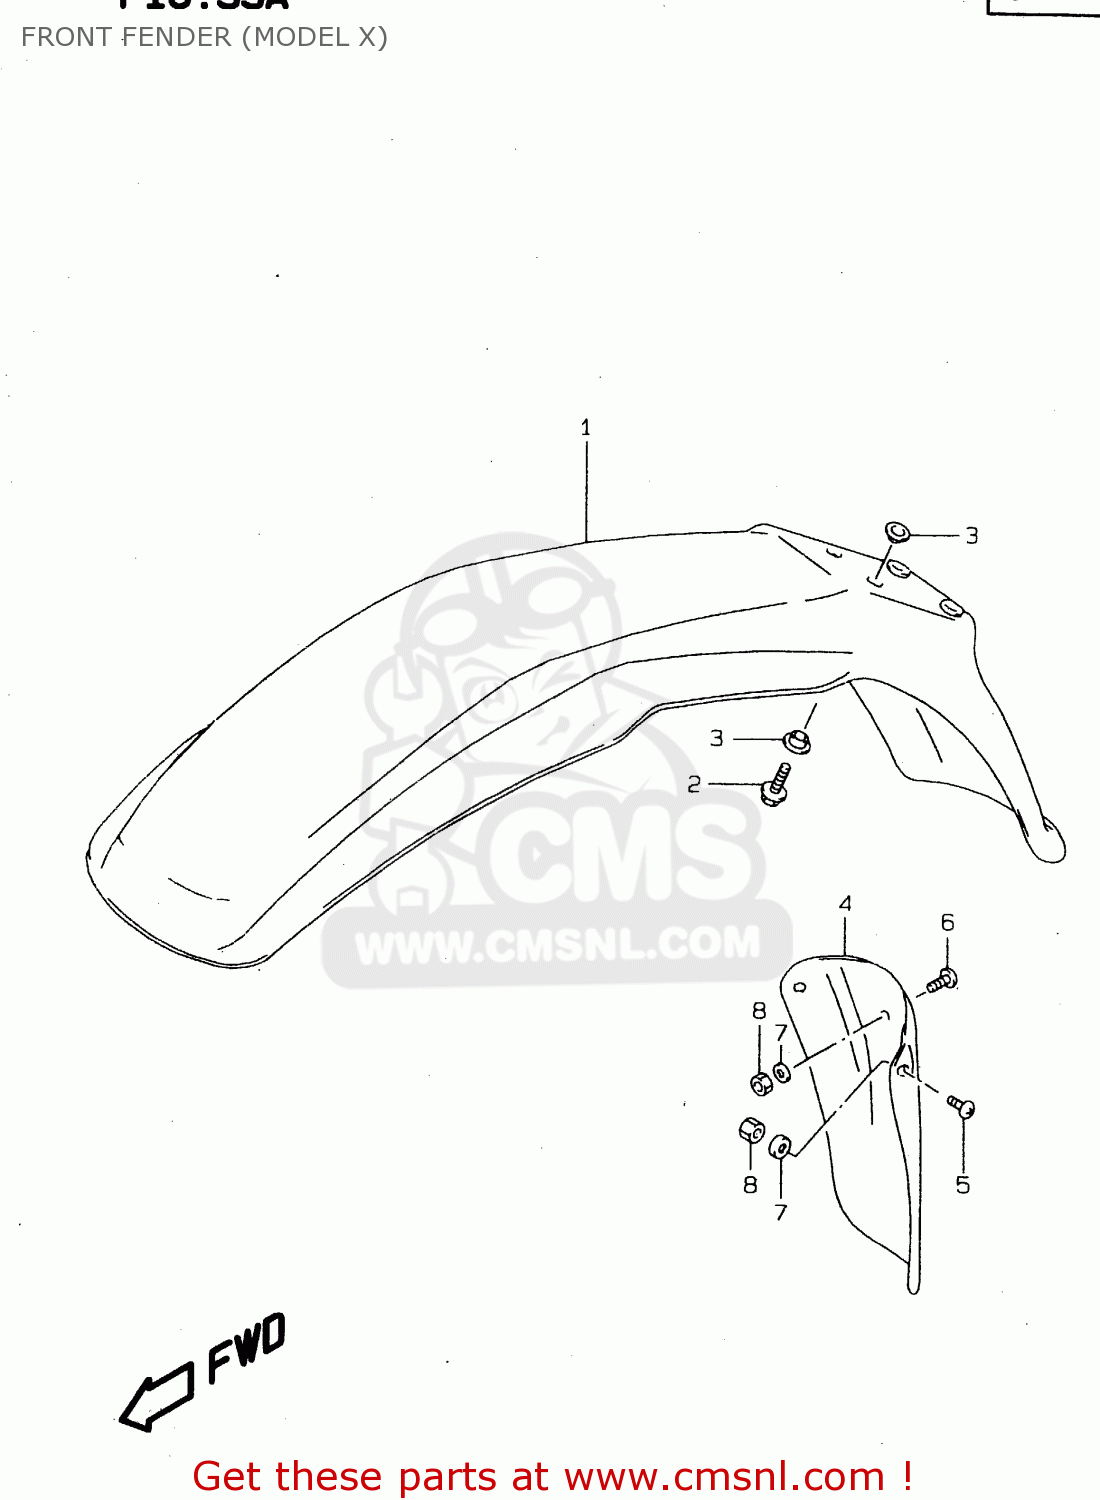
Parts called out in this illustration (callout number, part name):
1	FENDER,FR
2	BOLT
3	WASHER
4	MUDFLAP, FRONT FENDER
5	SCREW
6	SCREW
7	WASHER(6.5X16X1)
8	NUT
